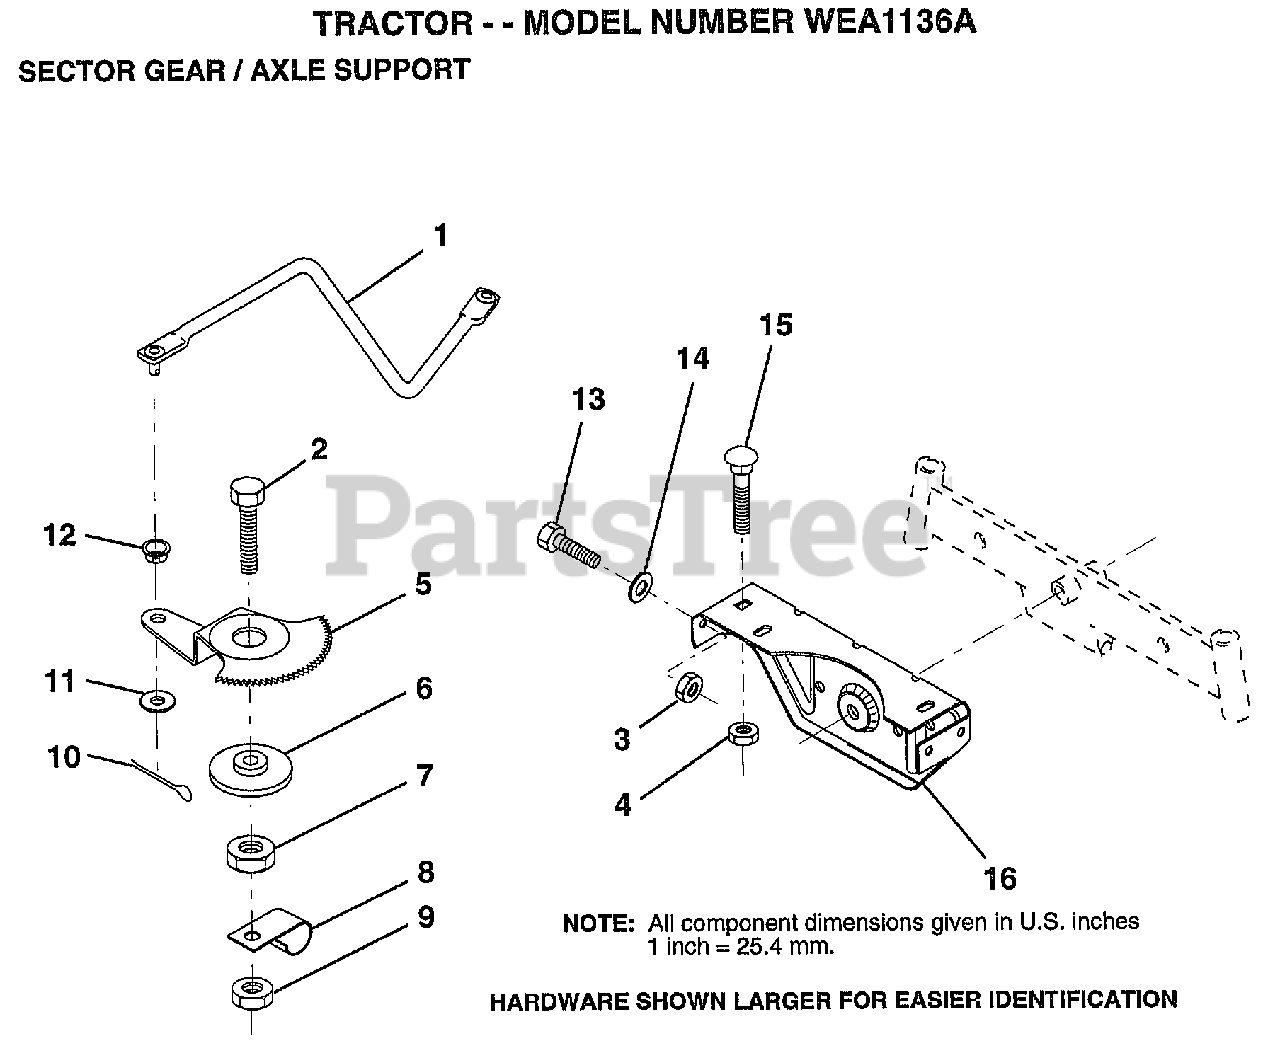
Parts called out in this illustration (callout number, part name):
1	DRAG LINK
2	"BOLT,HEX"
5	GEAR SECTOR
6	BUSHING
7	NUT
8	CLIP INSULATOR
9	NUT LTV
10	COTTER PIN
11	WASHER
12	BUSHING.DRAGLINK
13	BOLT
14	WASHER
15	BOLT
16	SUPT AXLE FRONT
